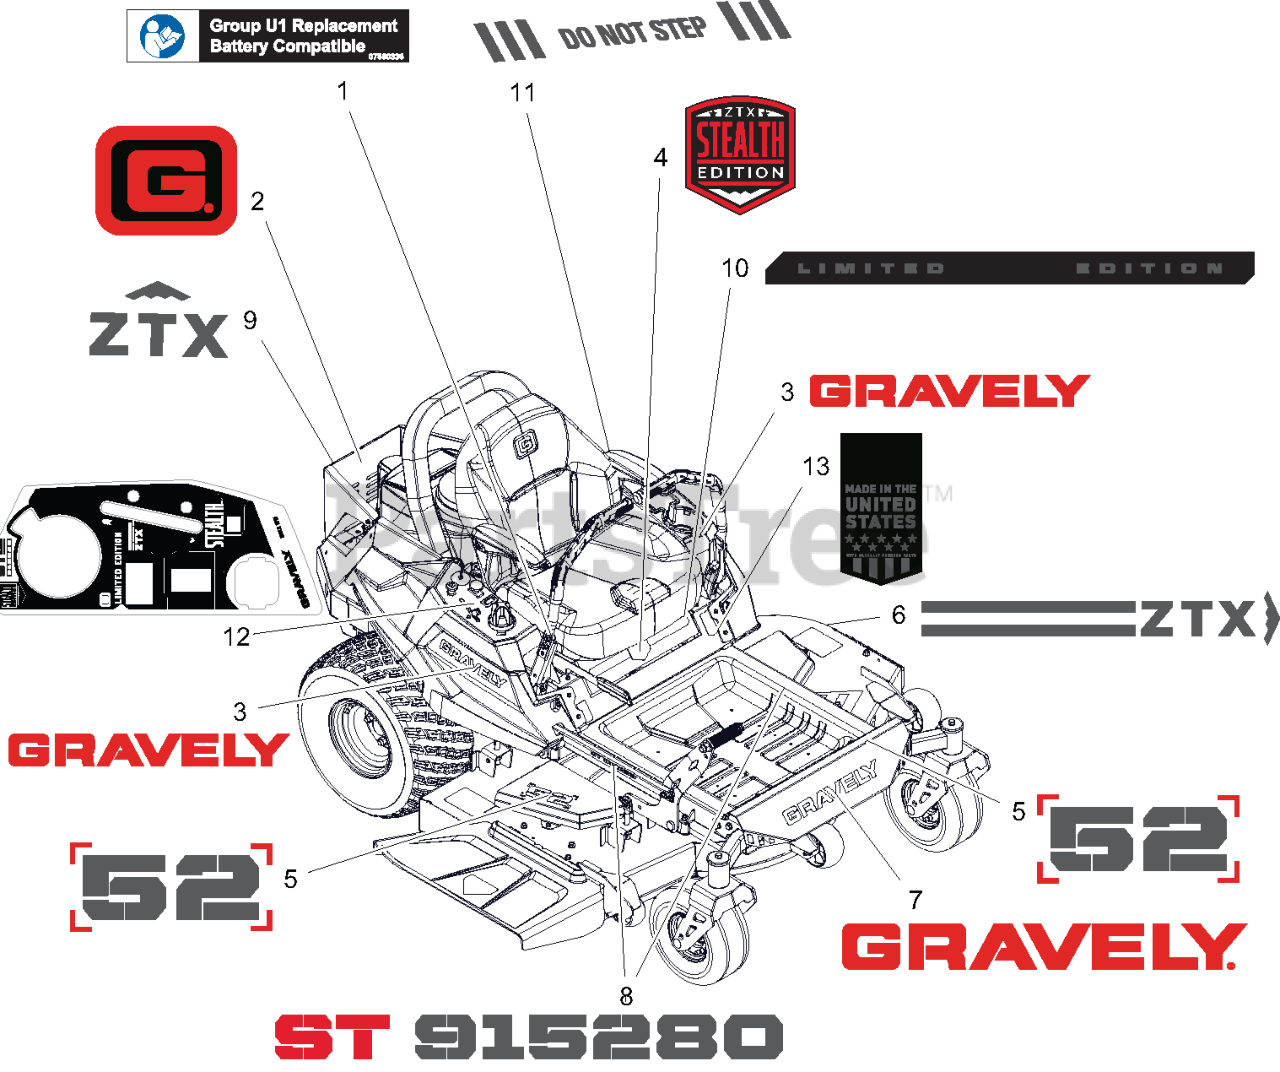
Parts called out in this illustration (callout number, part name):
1	DECAL, U1 BATTERY REPLACEMENT
2	DECAL- GRAVLEY
3	DECAL- GRAVELY
4	DECAL- GRAVELY STEALTH BADGE
5	DECAL- 52
6	DECAL- ZTX
7	DECAL, LIMITED EDITION GRAVELY
8	DECAL- ST 915280
9	DECAL- ZTX
10	DECAL- ZTX LIMITED
11	DECAL- DO NOT STEP
12	DECAL, LIMITED GRAVELY CTRL PNL
13	DECAL- MADE IN USA
